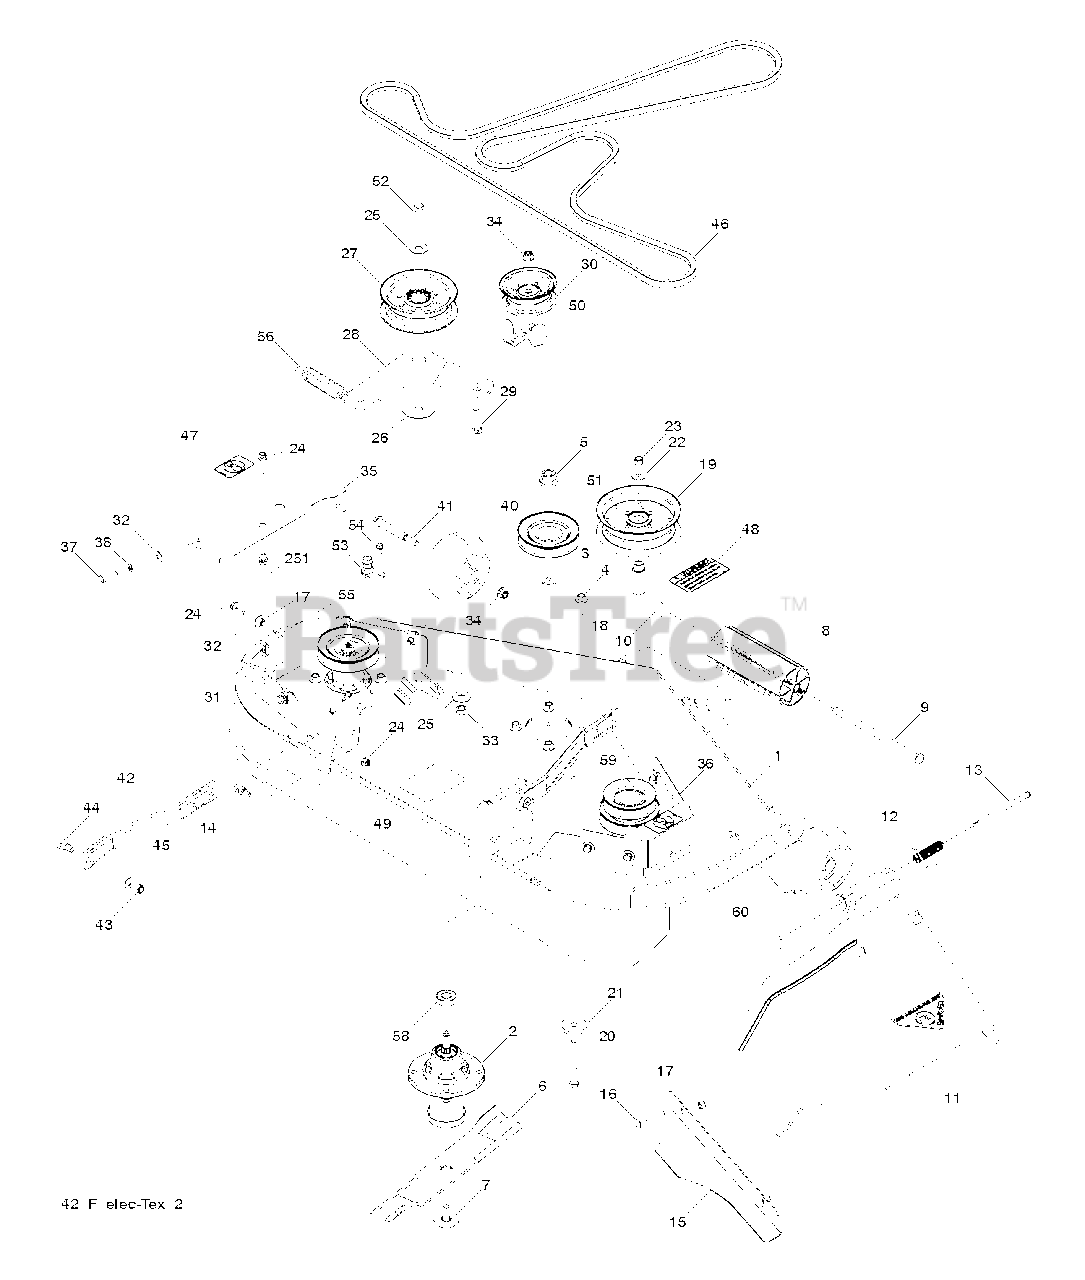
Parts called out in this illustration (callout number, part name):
1	DECK SVC W/DECALS 42 YTH ORNGE
2	MANDREL.DECK.ASSEMBLY
3	WASHER-SPACER
4	WASHER HEAD SCREW
5	LOCKNUT - 9/16
6	BLADE, 14 5/8"
7	BOLT.WASHER.ASM.7/16-2
8	NOSE ROLLER 48"
9	ROD.ROLLER.NOSE.NARROW.48"
10	PIN.COTTER.5/16.BOW TI
11	DISCHARGE CHUTE - 42 PLASTIC
12	SPRING - TORSION
13	PIN, CLEVIS 5/16 X 5.19
14	STUD.FASTNER.W/ANTI-ROTATE
15	CONFINEMENT.PLATE.42".BLACK
16	CARRIAGE BOLT 5/16C X 5/8"
17	NUT 5/16 NYLOC
18	BUSHING, IDLER
19	PULLEY, IDLER
20	HCS 3/8-16 X 3-1/2 GR5 ZD
21	SPINDLE WASHER
22	RP WASHER 3/8 FLAT
23	NUT 3/8-16 NYLOC
24	5/16-18 NYLOC FLANGE NUT
25	WASHER 7/16 FLAT ZD
27	PULLEY.IDLER.MWR.STATI.LH
28	ARM IDLER RAW
29	RHSNB 3/8-16X1-3/4
30	PULLEY.IDLER.FLAT
31	U-CLIP 5/16-18 NUT RETAINER
32	WASHER 5/16 FLAT
33	NUT 7/16-14 HEX WHIZ LK
34	NUT 3/8-16 HEX FLG NYLOC ZD
37	HCS 5/16C X 1
38	WASHER 5/16 LOCK
40	GAUGE WHEEL
41	SHOULDER BOLT 1/2X2-5/8 ZD SPE
42	ARM.SUSPENSION.MOWER
43	NUT HEX 3/8-16 NYLON, THIN
44	SB 3/8-16 X 3/8 SKT HD ZD
45	WASHER 3/8 SAE FLAT
46	BELT, 42" FAB DECK
47	DECAL, NO STEP
48	DECAL, CAUTION
49	DECAL.MOWER.SCH.48/54
50	BELT GAURD
51	PULLEY, MANDREL 4.08 OP
52	BOLT 7/16-14 X 2-1/2 GR 5 ZD
53	PORT.WASHOUT
54	BOLT 1/4-20 X 1/2 HWST
55	EYE BOLT 5/16 X 3.50
58	BEARING, BALL
59	PULLEY, COLLECTION 42
60	RETAINER CLIP
251	KEEPER,DRIVE BELT
